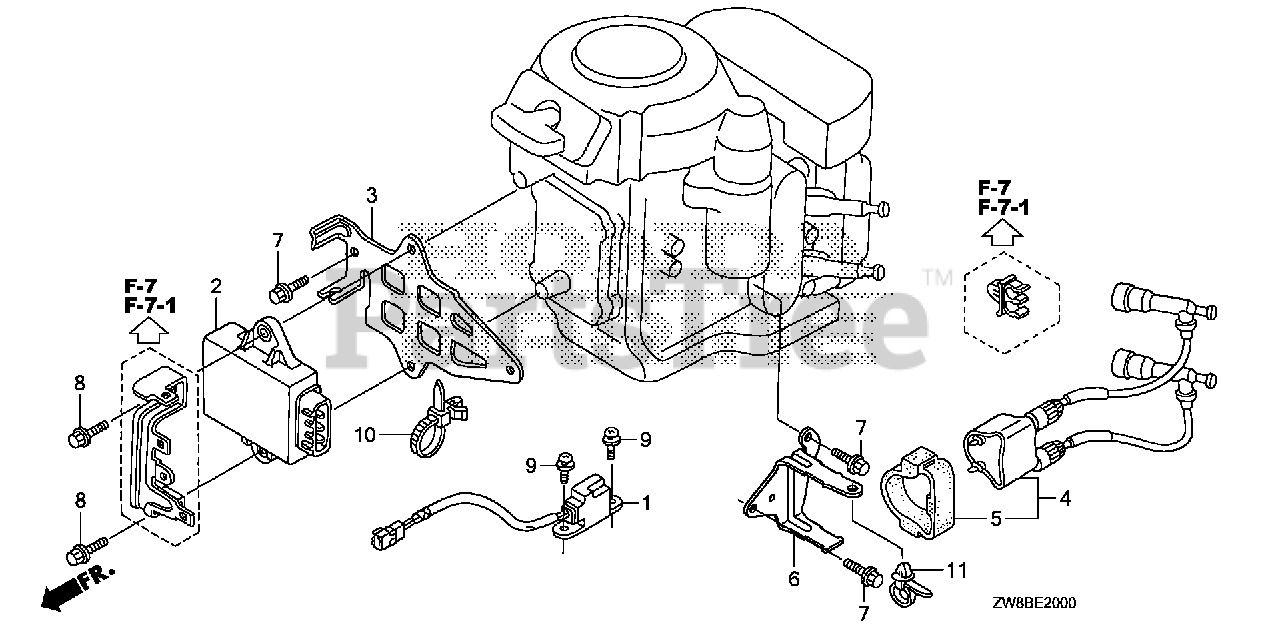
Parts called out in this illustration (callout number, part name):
1	COIL ASSY., PULSER
2	MODULE, IGNITION CONTROL (CDI)
3	PLATE, C.D.I.
4	COIL ASSY., IGNITION
5	SUSPENSION, IGNITION COIL
6	BRACKET, IGNITION COIL
7	BOLT, FLANGE (6X14) (CT200)
8	BOLT, FLANGE (6X25)
9	SCREW-WASHER (5X16)
10	STRAP, CABLE (118MM) (BLACK)
11	CLIP, HARNESS BAND (151.5MM) (NATURAL)
